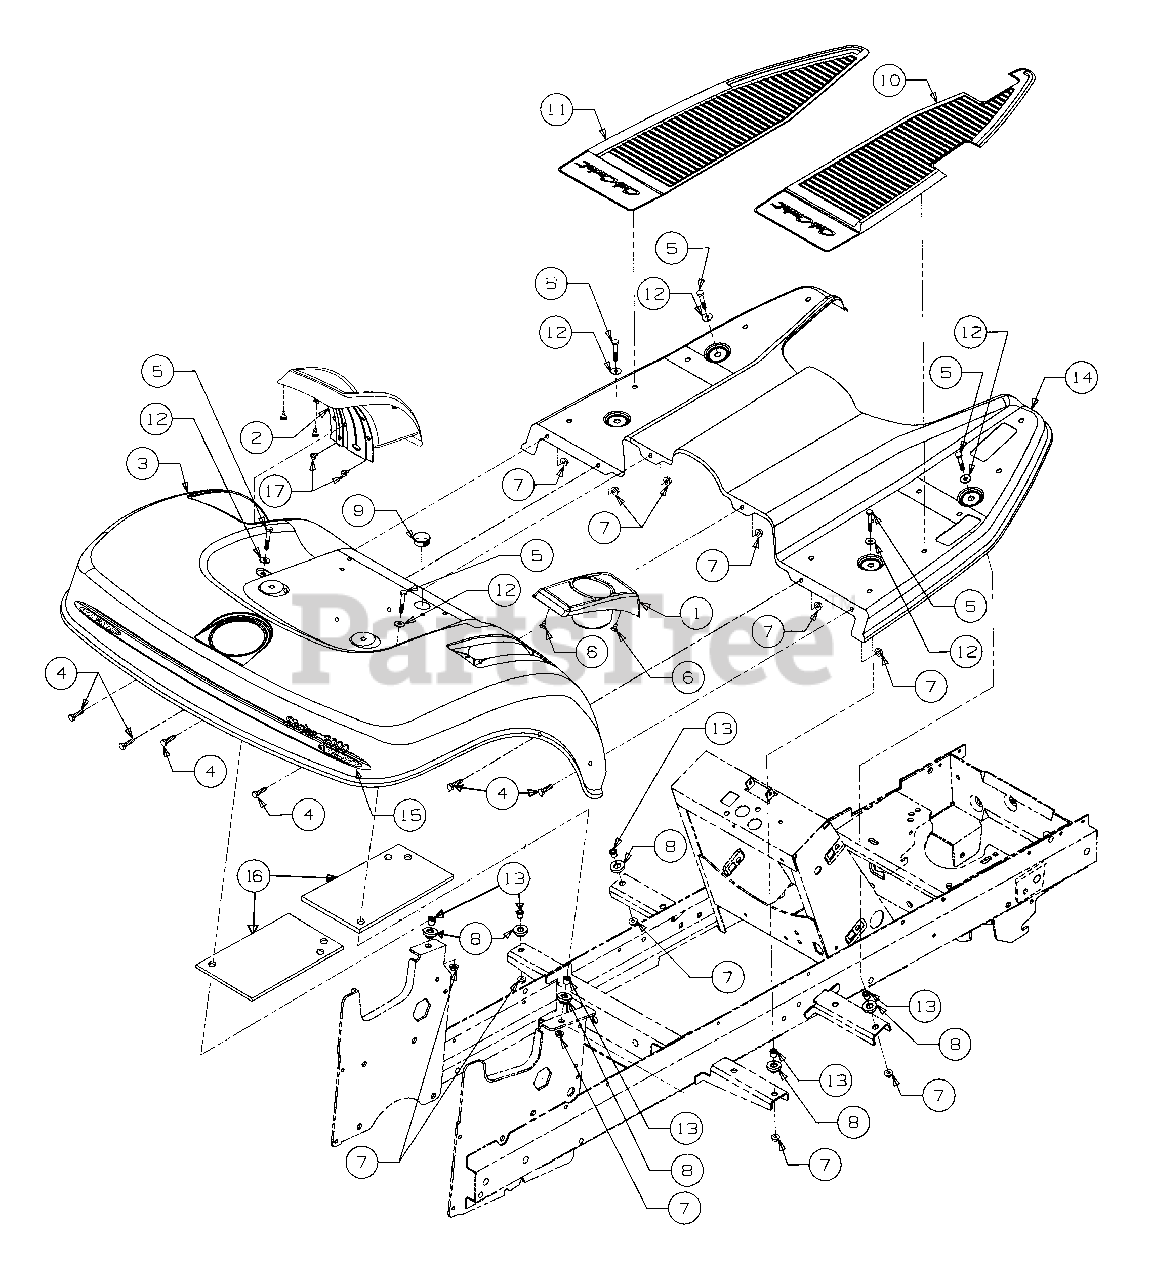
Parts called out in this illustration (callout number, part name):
1	Cup Holder
2	Cover, Implement Lift
4	Screw, Hex Cap, 1/4-20 x .62
5	Screw, Hex Cap, 1/4-20 x 1.0
6	Screw, Hex Tapp, #10 x .38 Lg
7	Nut, Hex Flange Lock, 1/4-20
8	Grommet, Insulator
9	Bushing, Snap, 7/8 ID
10	Pad, RH Foot
11	Pad, LH Foot
12	Washer, Flat, .255 x .72 x .06
13	Spacer, .28 ID x .40 OD x .42 Lg
14	Running Board w/Graphic
15	Graphic, Rear Fender
16	Bracket, Fender Reinforcement
17	Screw, Hex Tapp, #10-16 x .5
